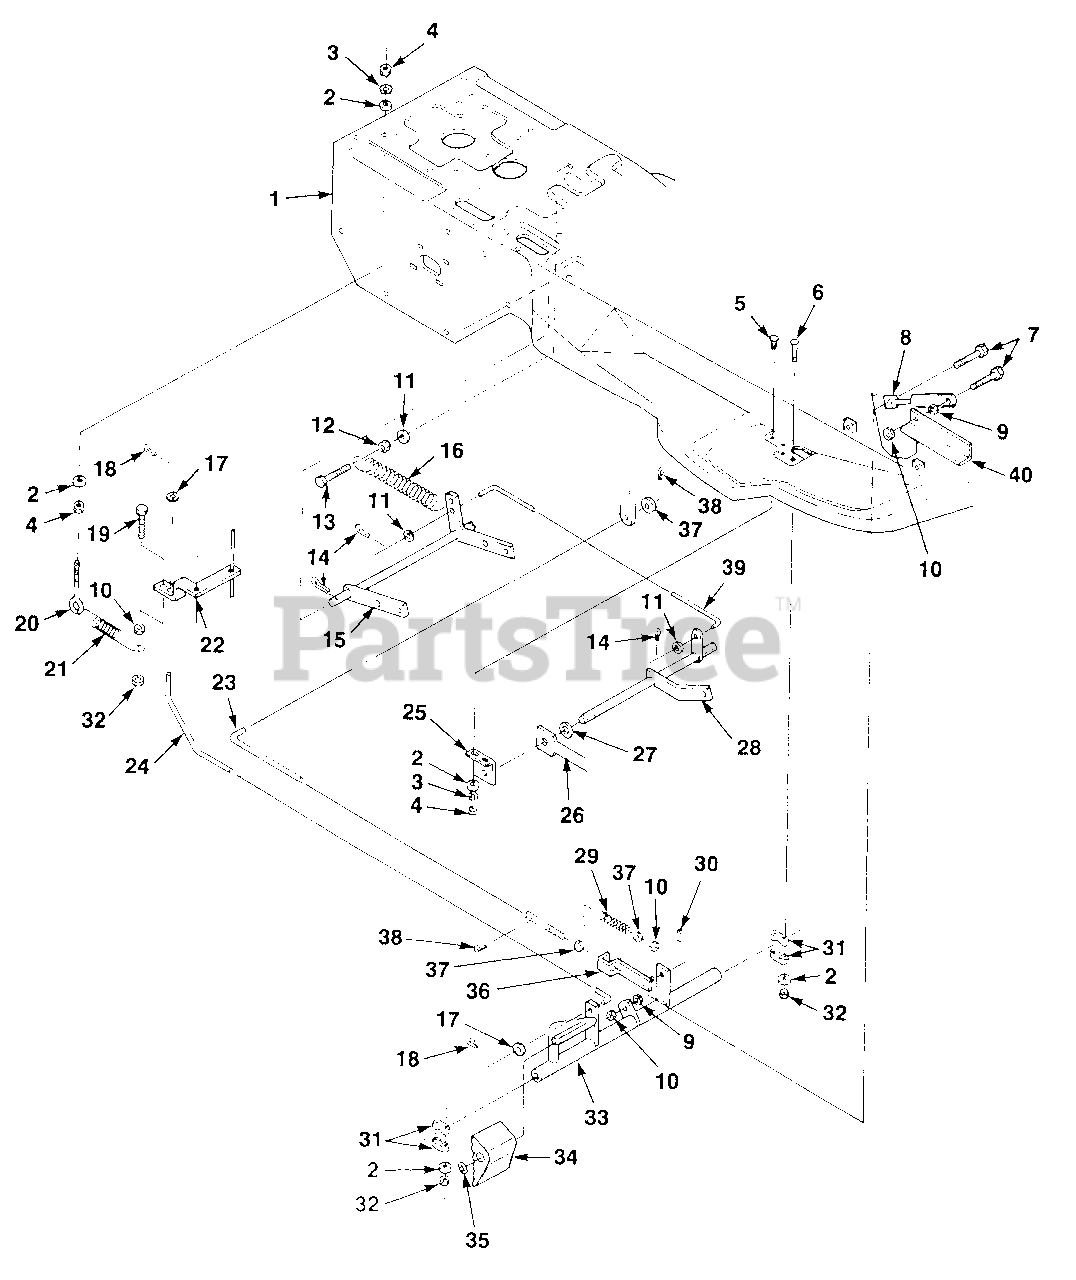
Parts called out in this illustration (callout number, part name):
2	WASHER- Flat 1/4"
3	WASHER- Lock 1/4"
4	NUT- Hex 1/4-20
5	BOLT- Rd. hd. 1/4-20 x .625
6	BOLT- Rd. hd. 1/4-20 x 1 1/2"
7	SCREW- Hex cap 5/16-18 x 1 1/2"
9	NUT- Hex 5/16-18
10	NUT- Hex centerlock 5/16-18
11	WASHER- Flat 3/8"
12	NUT- Centerlock 3/8-16
13	SCREW- Hex cap 3/8-16 x 2 1/4"
14	PIN- Cotter 7/16 x 1"
15	HANGER- Rear
17	WASHER- Flat 5/16"
18	PIN- Cotter
19	SCREW- Hex 5/16-18 x 1"
20	EYEBOLT- 1/4-20
21	SPRING- Extension
22	ARM- Idler
23	ROD- Brake
24	ROD- Clutch
25	BRACKET- Front hanger
26	SUPPORT- Front Axle
27	WASHER- Flat 1/2"
28	HANGER- Front
29	SPRING- Compression
30	PIN- Cotter
32	NUT- Hex centerlock 1/4-20
33	CLUTCH/BRAKE
34	PEDAL- Rubber
35	NUT- Push
36	BRACKET- Brake spring
37	WASHER- Flat 5/16"
38	PIN- Cotter 3/32 x 1"
39	ROD- Lift
40	BRACKET- Damper
